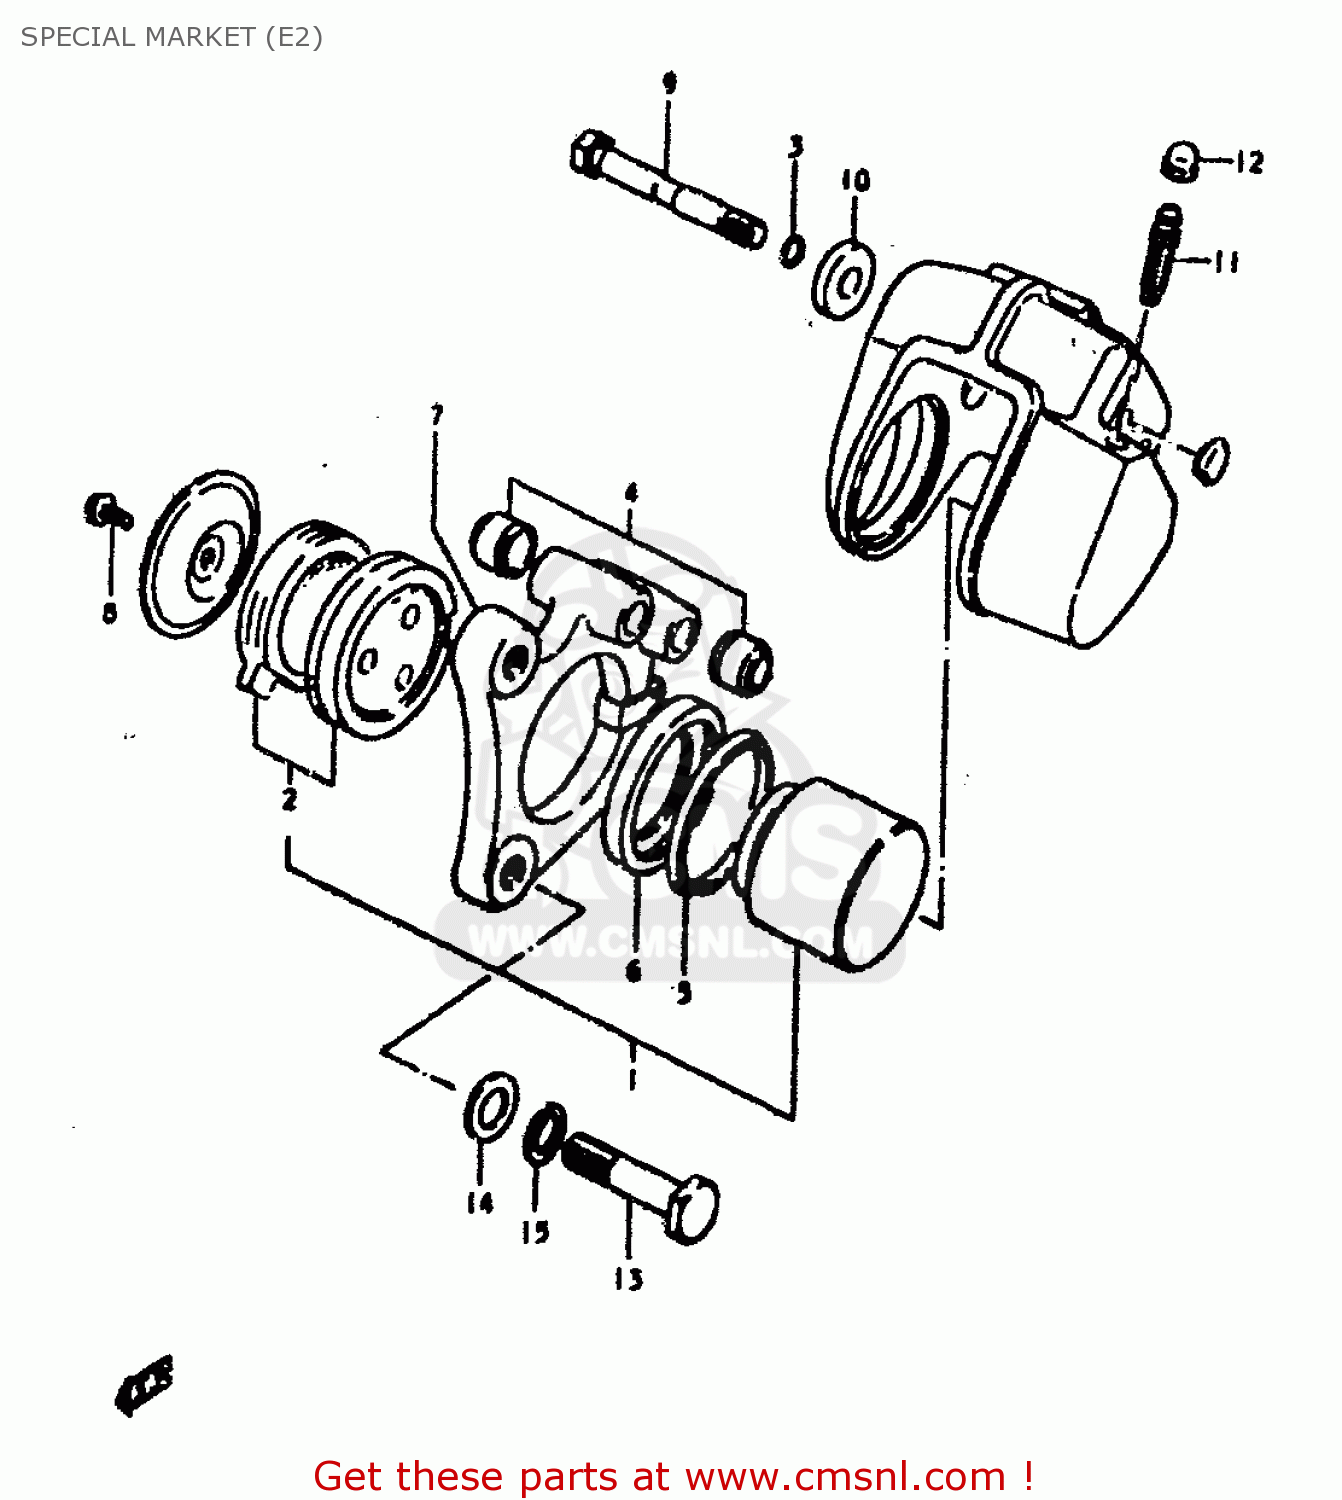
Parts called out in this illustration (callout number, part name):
1	PISTON/PAD SET
2	PAD SET (MCA)
3	O RING
4	COVER,AXLE DUST
5	SEAL,FR CALIPE
6	BOOT,PISTON
7	HOLDER,CALIPERS
8	SCREW 6X12
9	AXLE,CALIPER
10	WASHER,AXLE
11	BLEEDER
12	CAP,BREATHER
13	BOLT
14	WASHER
15	LOCK WASHER
